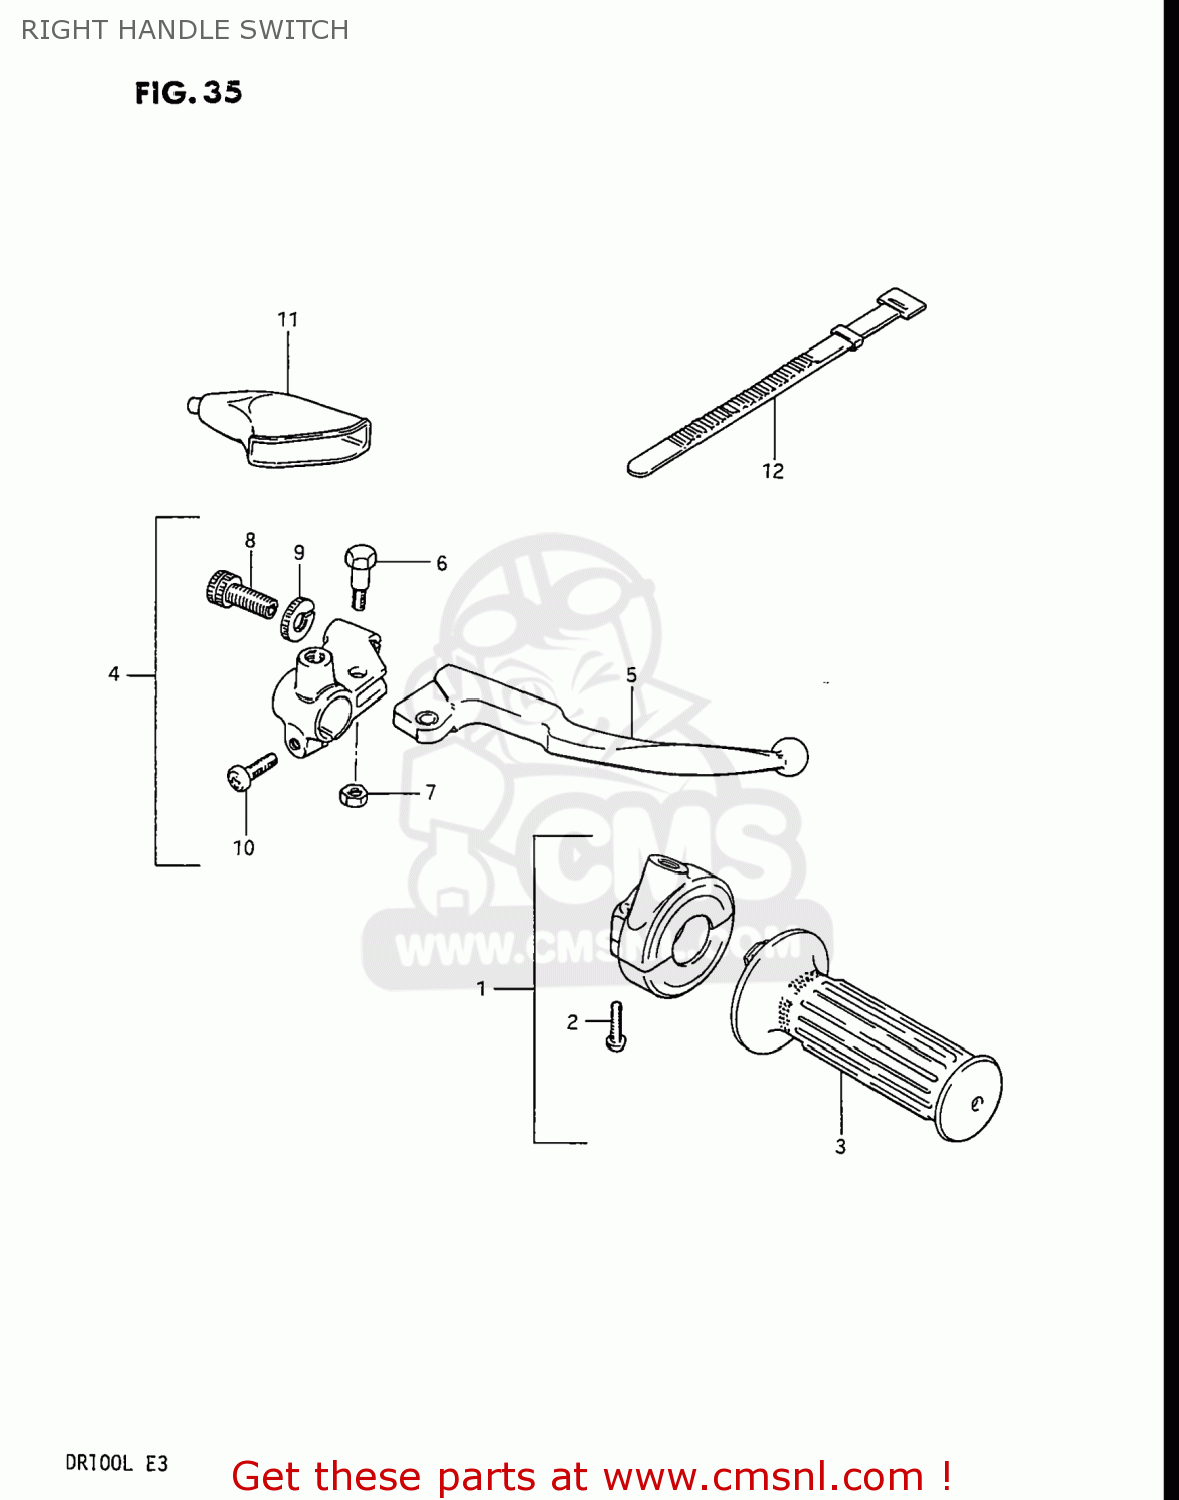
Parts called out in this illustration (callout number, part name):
1	CASE ASSY,THROTTLE
2	SCREW 5X20
3	GRIP,THROTTLE
4	LEVER ASSEMBLY,BRAKE
5	LEVER,BRAKE
6	BOLT,LEVER
7	NUT 6MM
8	ADJUSTER,CABLE
9	NUT,CABLE ADJUSTER
10	SCREW
11	COVER,CLUTCH LEVER
12	CLAMP(L:120)
